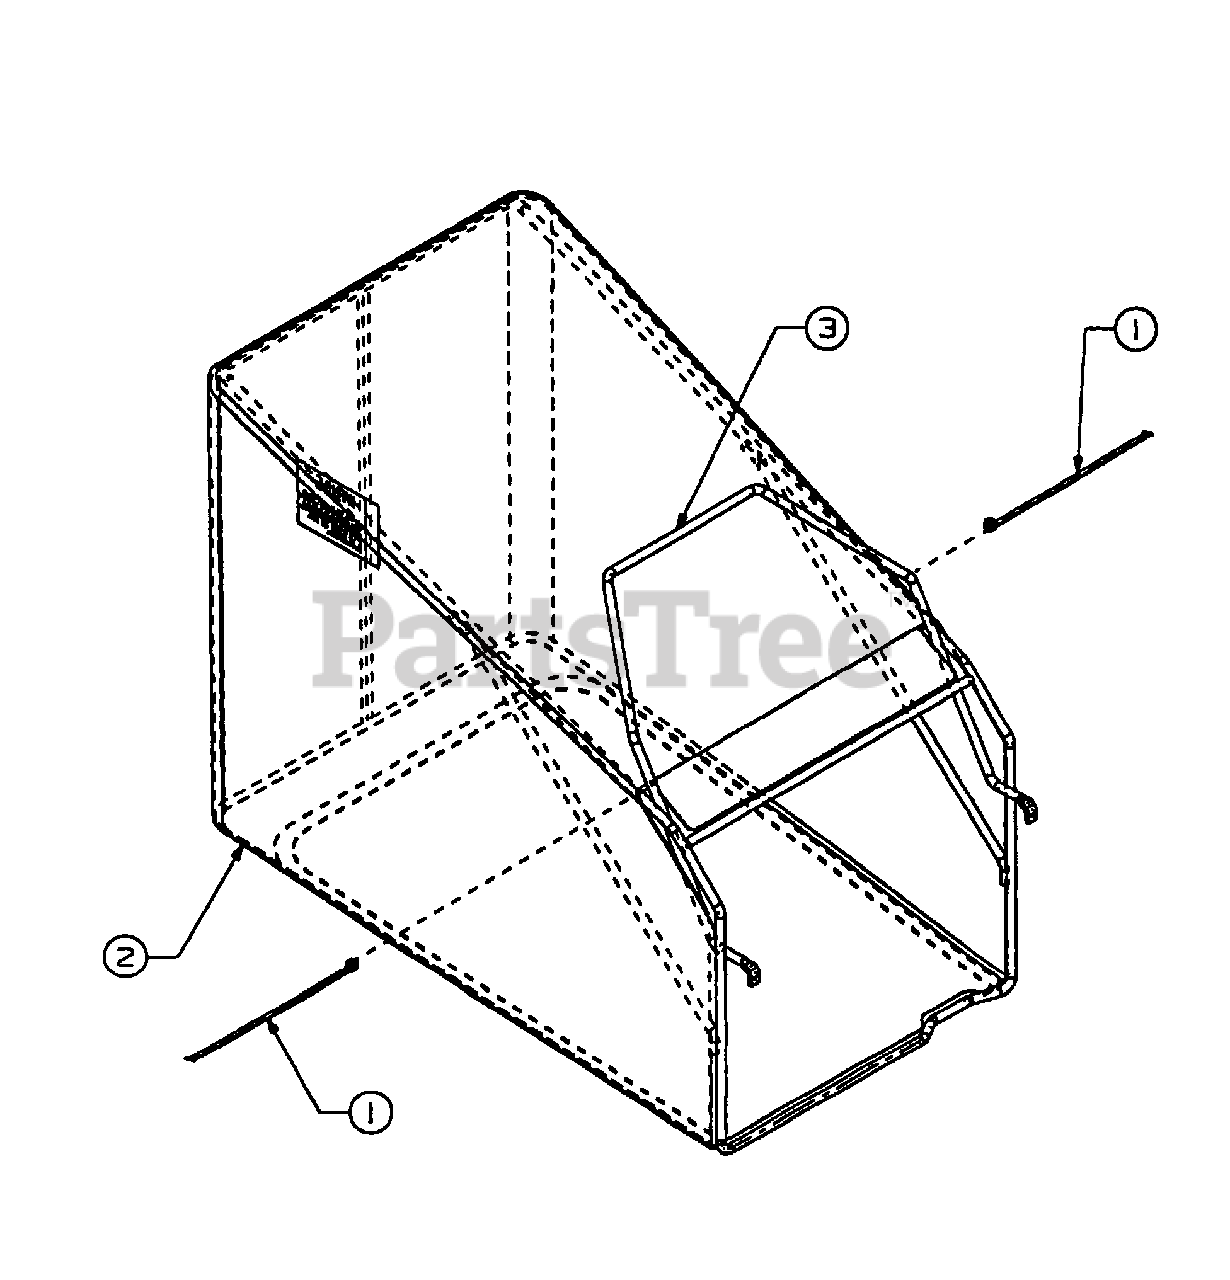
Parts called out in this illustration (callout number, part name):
1	CBL: TIE:3/16 X .05 X 7.4
2	GRASS BAG ASM:RD: COMMERCIAL
3	FRAME:GRASS BAG:21" RD (BLACK)
